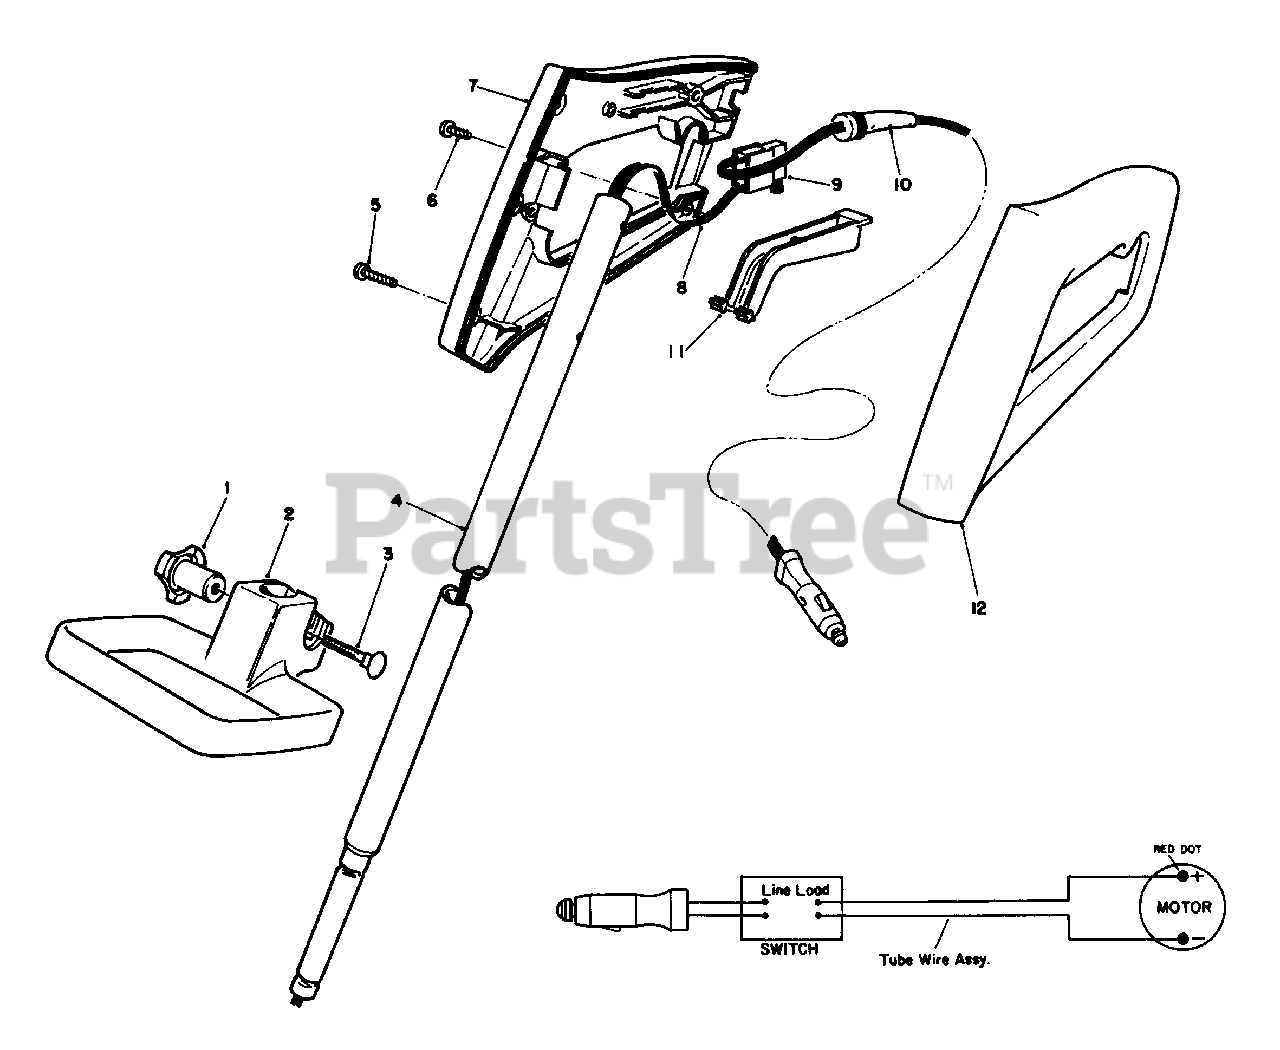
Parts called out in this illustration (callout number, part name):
1	Knob-Adjust
2	Handle-Adjust
3	Bolt-Carriage
4	Tube-Handle
5	Screw-Thread Forming
6	Screw-Thread Forming
7	Grip-Handle, R.H.
8	Wire Assembly-Tube
10	Cord Assembly-Tube
11	Bar-Switch
12	Grip-Handle, L.H.
